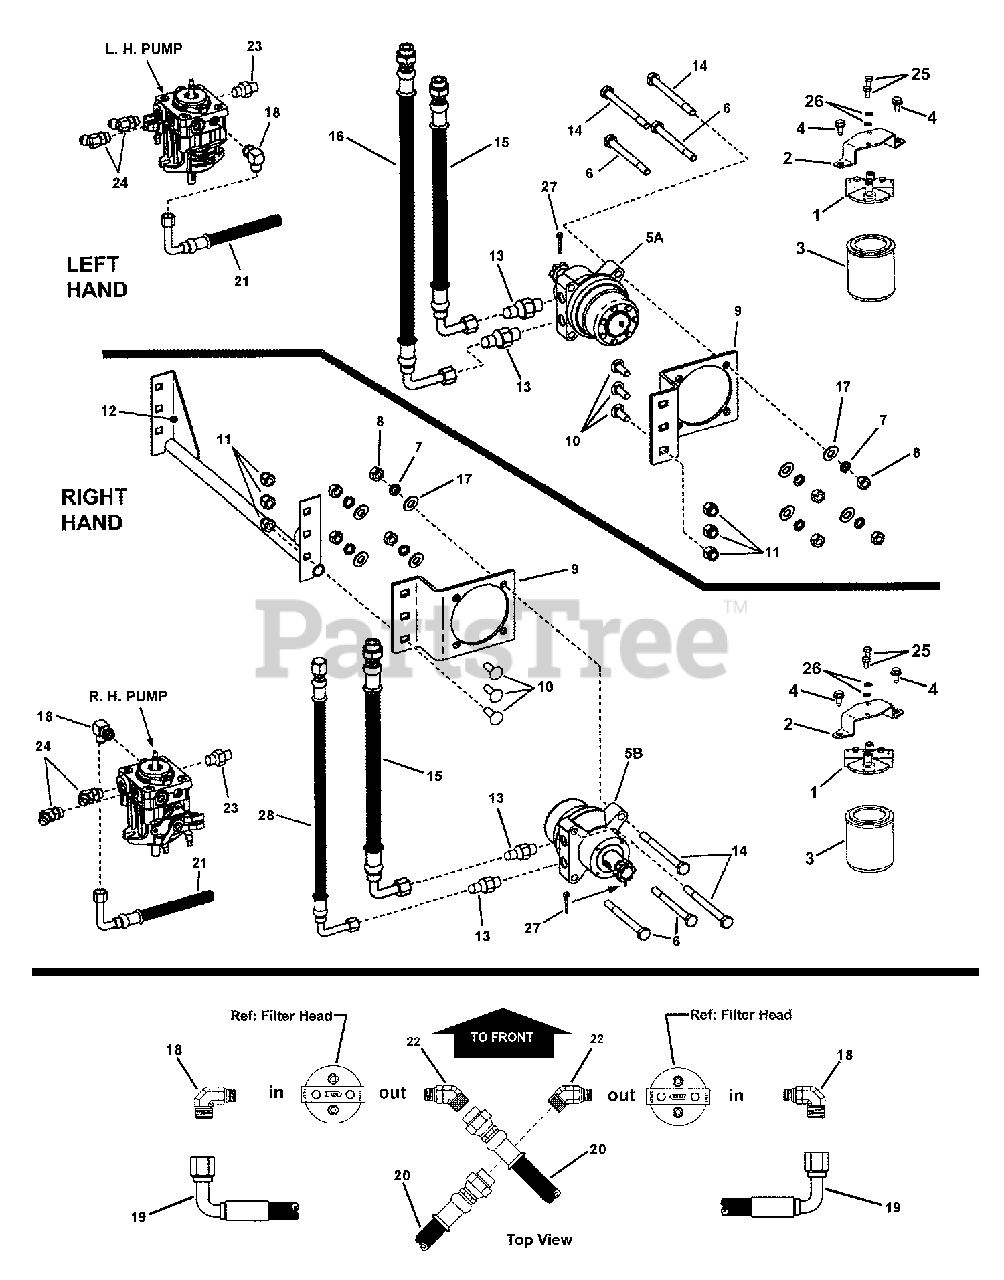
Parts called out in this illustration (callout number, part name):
1	FILTER HEAD
2	BRACKET, Filter
3	FILTER, OIL
4	SCREW, 5/16-18 x 5/8" Hex Washer Self-Tap
5A	MOTOR, Hydraulic, Left Hand
5B	MOTOR, Hydraulic, Right Hand
6	BOLT, 1/2-13 x 6" Hex Head Cap, GR 5
7	WASHER, 1/2" Split Lock
8	NUT, 1/2-13 HEX
9	PLATE, Mounting
10	BOLT, 1/2-13 x 1-1/2" Square Neck Carriage, GR 5
11	NUT, 1/2-13 Hex Nyloc
12	WELDMENT, Rear Crossbrace
13	CONNECTOR, Straight Hydraulic (Parker # 8-10 F5OLO-S)
14	BOLT, 1/2-13 x 3-3/4" Hex Head Cap
15	HOSE, 15-1/2" Hydraulic (Parker # F436JCJ9080808-15.50)
16	HOSE, 17-1/2" Hydraulic (Parker # F436BKJCJ5080808-17.5)
17	WASHER, .531 I.D. Flat
18	CONNECTOR, 90-Degree Hydraulic (Parker # 8-6 C5OLO-S)
19	HOSE, 18-1/2" (Parker # R836BKJCJ9090808-18.5)
20	HOSE, 12-1/4" (Parker # R836BKJ9NR080008-12.5)
21	HOSE, 6-1/2" (Parker # R836BKJ9NR080008-6.5)
22	CONNECTOR, 45-Degree Hydraulic (Parker #8-6 V 50L0-S)
23	CONNECTOR, Straight Hydraulic (Parker # 8-6 F5OLO-S)
24	CONNECTOR, 45-Degree Hydraulic (Parker # V5OLO-S)
25	SCREW, 1/4-20 x 1/2" Hex Head Cap, GR 5
26	WASHER, 1/4" Split Lock
27	PIN, 1/8 x 1-1/2" Cotter
28	HOSE, 19-1/2" (Parker # F436BKJCJ5080808)
